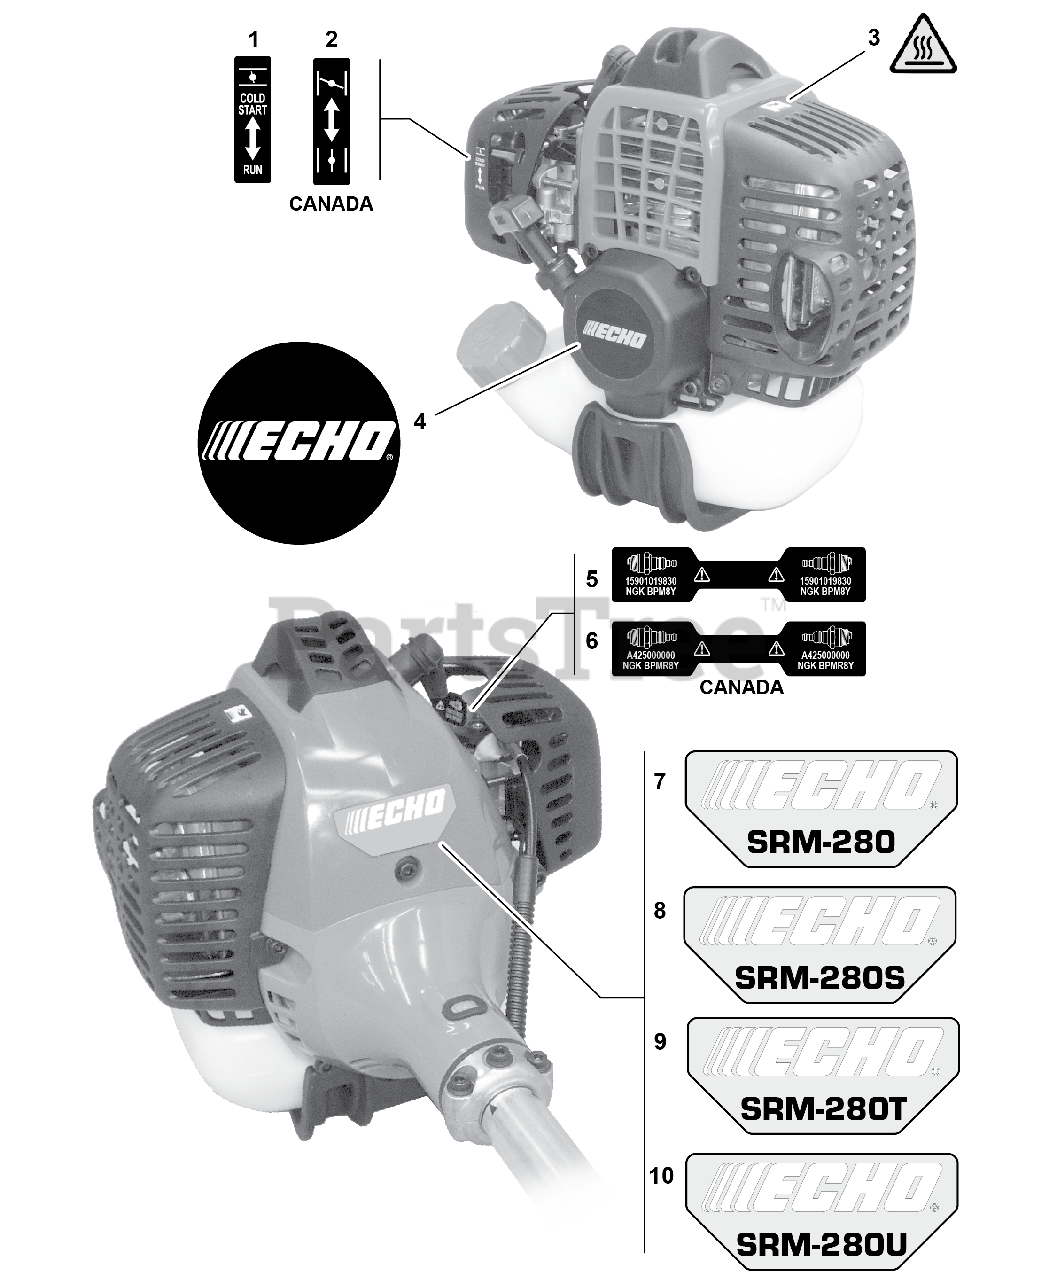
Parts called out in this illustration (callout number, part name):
1	LABEL - CHOKE
2	LABEL - CHOKE
3	LABEL - CAUTION -- HOT
4	LABEL - ECHO
5	LABEL - SPARK PLUG -- BPM8Y
6	LABEL - SPARK PLUG -- BPMR8Y
7	LABEL - MODEL -- SRM-280
8	LABEL - MODEL -- SRM-280S
9	LABEL - MODEL -- SRM-280T
10	LABEL - MODEL -- SRM-280U
